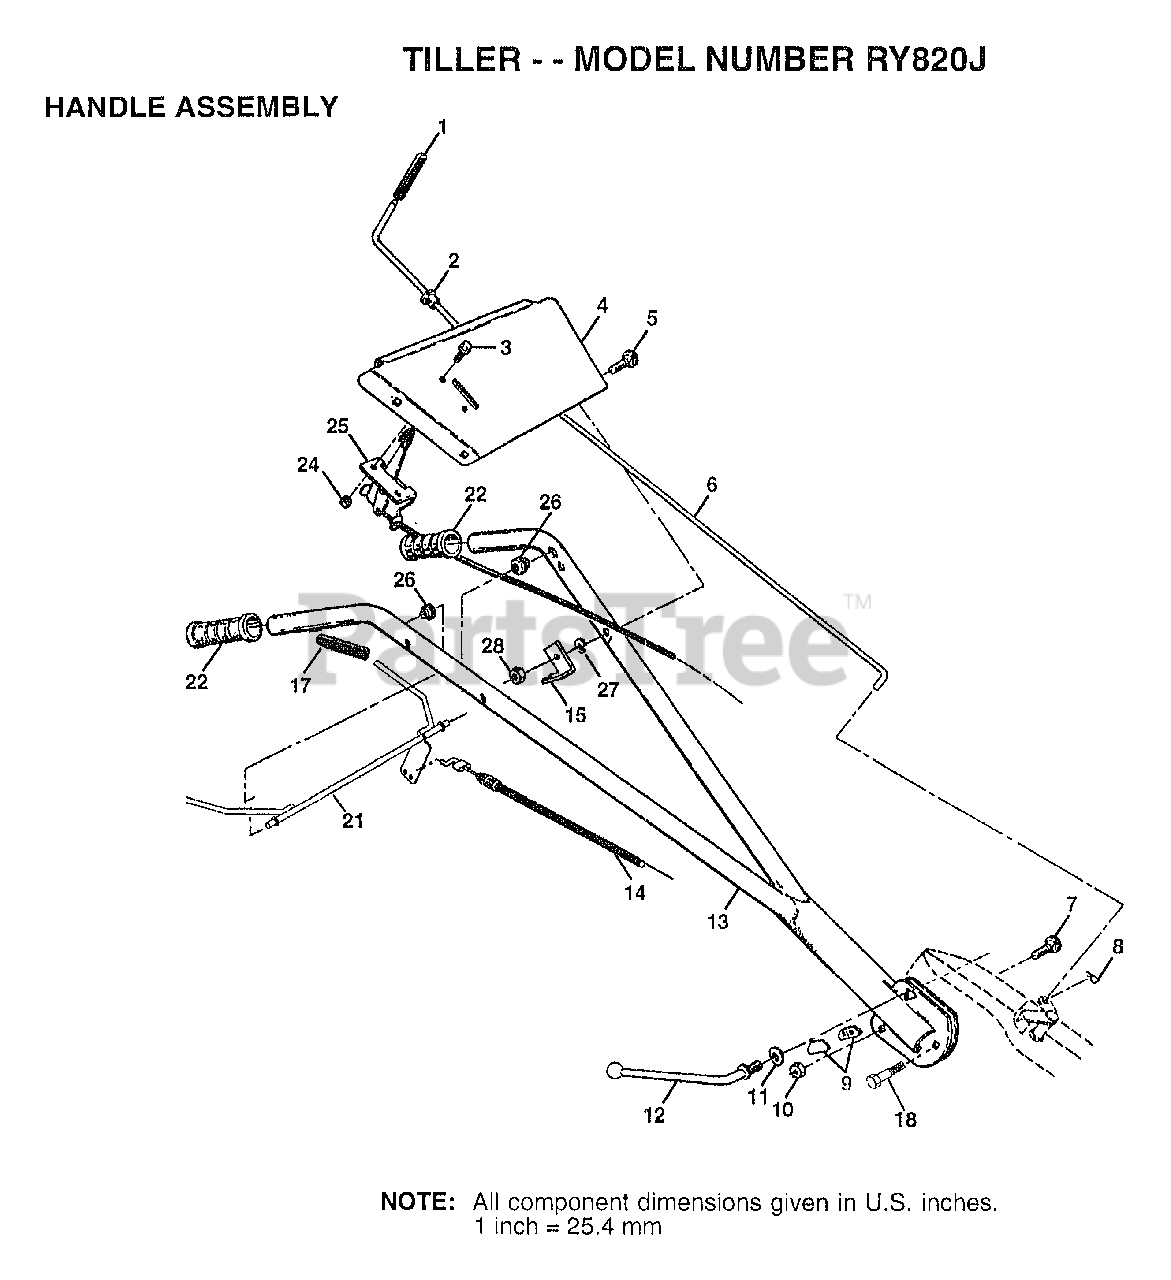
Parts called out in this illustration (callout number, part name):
1	GRIP TI
2	BUSHING
3	SCREW.PNHD.10-24
4	HANDLE BRACKET
5	BOLT CARRIAGE CRT
6	ROD SHIFT CRT
7	BOLT D
9	LOCK CRT
10	LOCKNUT
11	WASHER CRT
12	LEVER LOCK CRT
14	"CABLE, CLUTCH"
15	BRACKET.CLUTCH.CA
17	GRIP BAR CRT
18	BOLT PIVOT
21	BAR CONTROL
22	"GRIP,HANDLE"
25	"CONT,THROTTLE"
26	GROMMET.HANDLE.V-
27	LOCKWASHER
28	NUT
